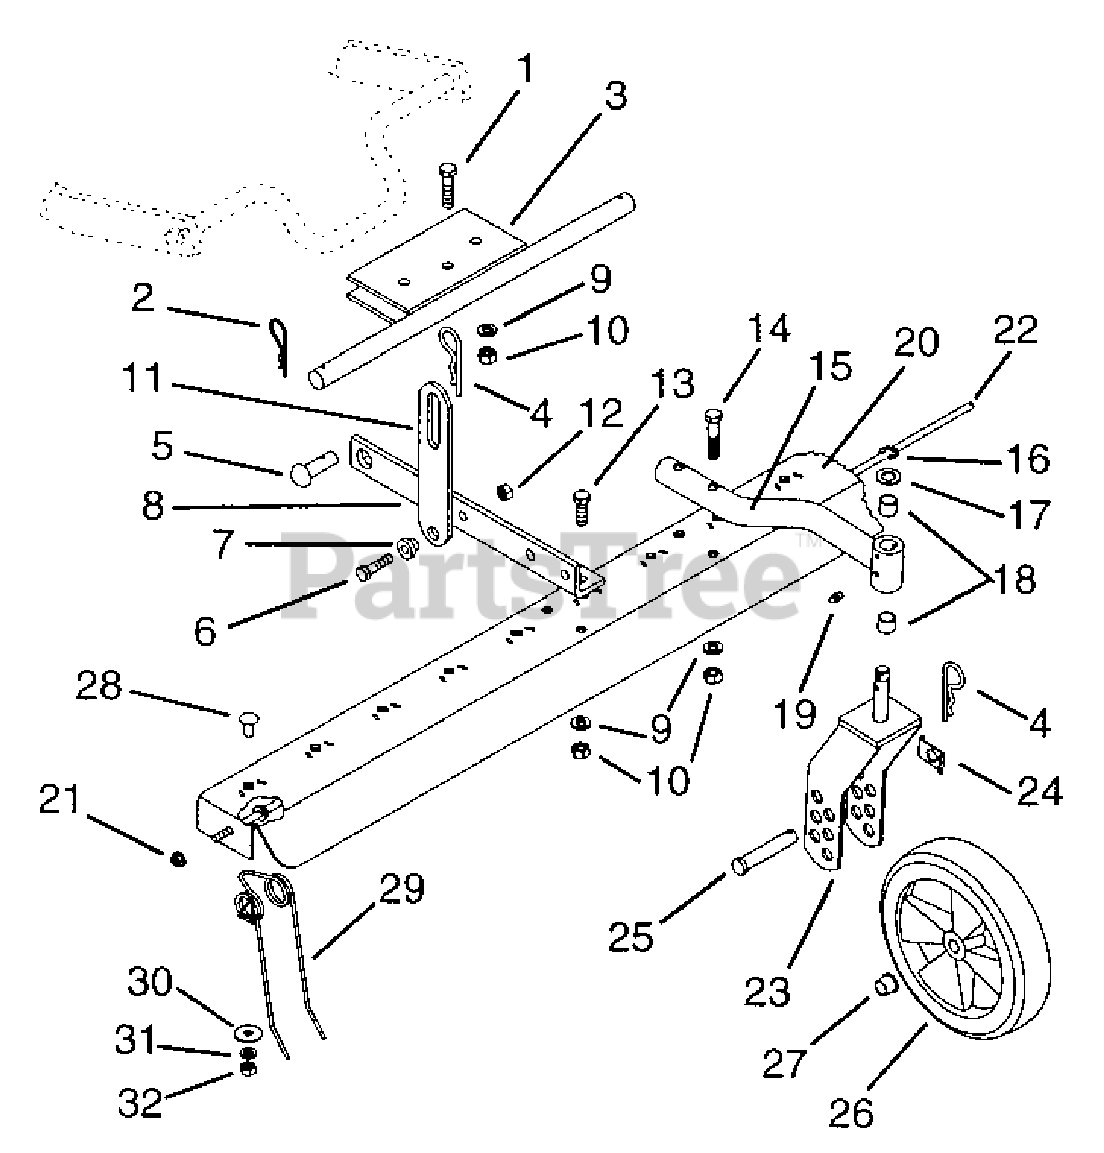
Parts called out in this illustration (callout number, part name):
1	@BLT-HEX .38-16X1.50 GR5 YWZC
2	HAIRPIN, #7 CLIP .094X2.31 YWZ
3	BRACKET WELDMENT
4	PIN-HAIR-INT .15X2.937 YWZC
5	PIN-CLEV .50X1.25 RH ST PL
6	@BLT-HEX .31-18X1.25 GR5 YWZC
7	BSHG-FLG .344X.468X.485X.750
8	ANGLE BRACKET
9	@WSHR-LK .38X.094 REG YWZC
10	@NUT-HEX .38-16 YWZC
11	LIMITING ARM
12	@NUT-HEX .31-18 YWZC
13	@BLT-HEX .38-16X1.00 GR5 YWZC
14	@BLT-HEX .38-16X1.75 GR5 YWZC
15	WHEEL BRACKET WELDMENT
16	RG-RTNG-EXT .438X.035
17	@WSHR-FL-STL.531X1.06X.095YWZC
18	BSHG-SLV .500X.625X.500
19	FTG-LUBE .25-28X.256 YWZC
20	CHANNEL
21	@NUT-LK-CTR .25-20 YWZC
23	WHEEL YOKE WELDMENT
24	AXLE TAB
25	PIN-CLEV .494X2.62 YWZC
26	WHL 7.50" .50 BORE, 1.50 HUB
27	BSHG-FLG .500X.625X.500X.750
28	@BLT-RDHDSQNK .31-18X.75 G5YZ
30	WSHR-FL-STL .328X1.0X.094 YWZC
31	@WSHR-LK .31X.078 REG YWZC
32	@NUT-HEX .31-18 YWZC
